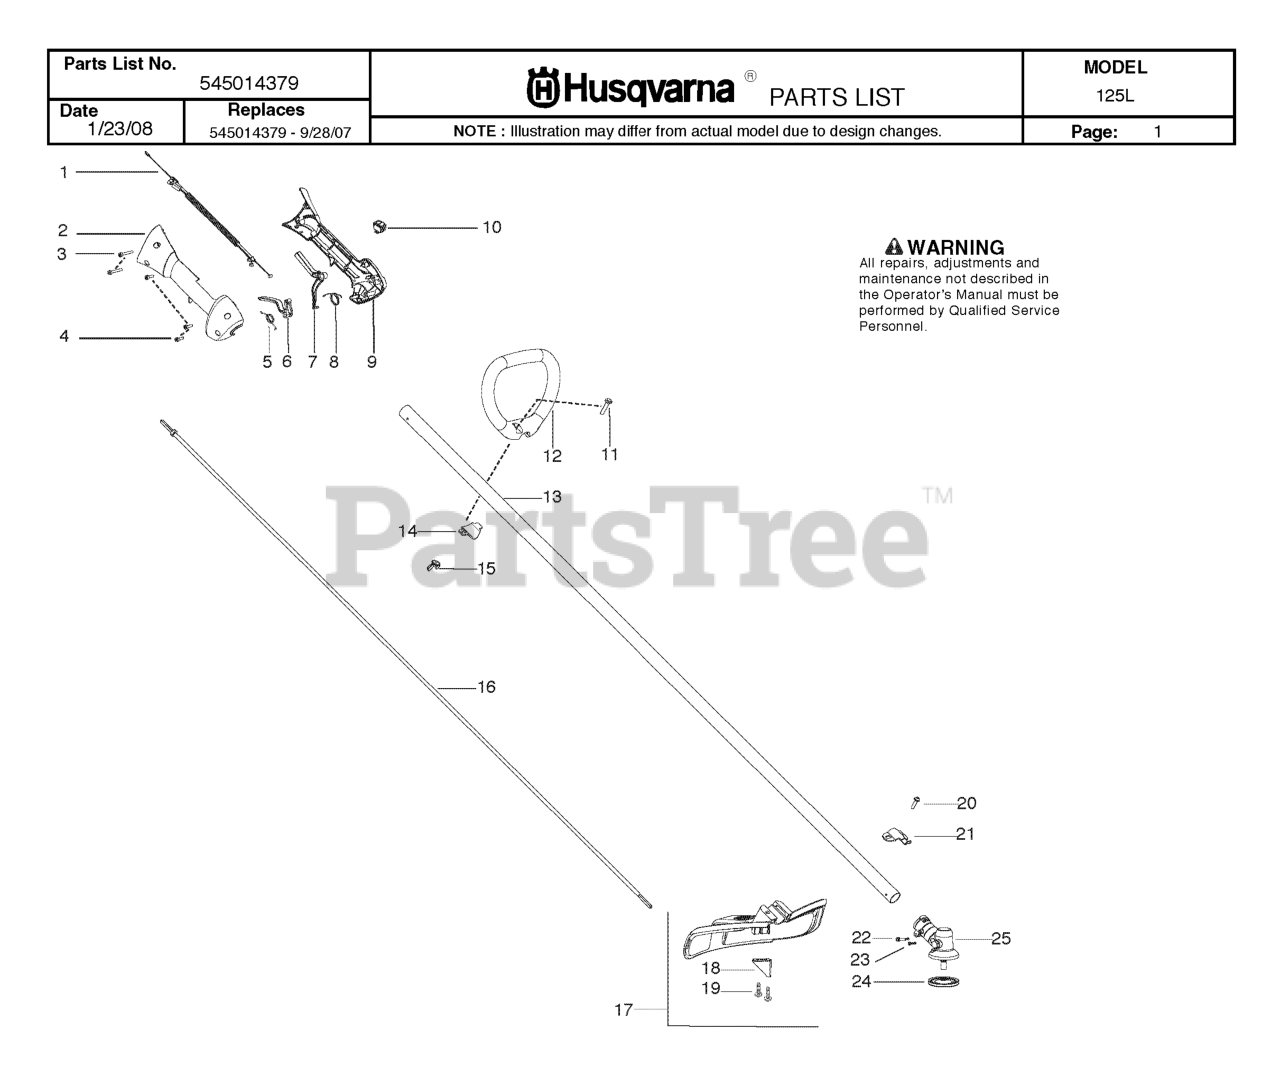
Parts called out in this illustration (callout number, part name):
1	ASSY-CABLE WIRE HARNESS
1	KIT-AIR BOX W/CABLE WIRE HARN
2	HOUSING-THROTTLE RH
4	SCREW M4 X 1.75 PT 16MM
5	SPRING TRIGGER
6	TRIGGER THROTTLE
7	THROTTLE LOCKOUT
8	SPRING LOCKOUT
9	HSG THROTTLE LH
10	KIT SWITCH
11	BOLT, TYPE 2
13	KIT DRIVESHAFT SST
14	CLAMP ASSIST HANDLE
15	WINGNUT, TYPE 2
16	FLEXSHAFT 57
16	KIT, CLUTCH DRUM & FLEXSHAFT
17	KIT COBI SHIELD
18	Limiter - Line
20	SCREW 1/4-20 X 7/8 (TAP
21	BRACKET SHIELD STRAIGHT SHAFT
22	SCREW - CARB. ADAPTOR
24	DRIVE DISC
25	ASSY GEARBOX
